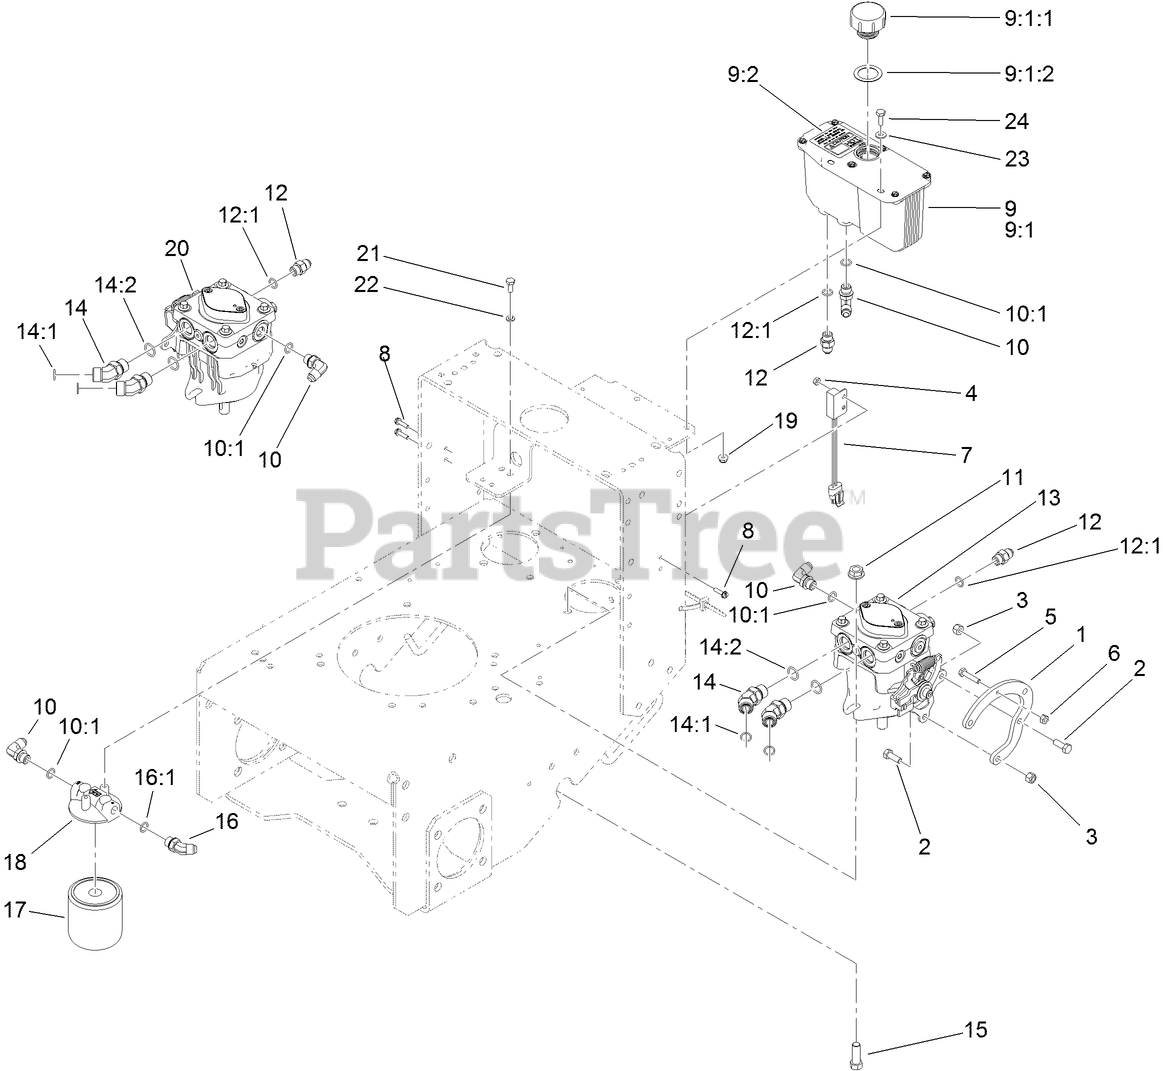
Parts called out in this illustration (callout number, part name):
1	BRACKET-ADAPTER, PUMP
2	SCREW-HH
3	NUT-LOCK, NI
4	NUT-LOCK, NI
5	SCREW-HH
6	NUT-HEX
7	SWITCH-PROXIMITY
8	SCREW-HWH
9	HYD RESERVOIR ASM
9:1	Reservoir-HYD
9:1:1	CAP-RESERVOIR, HYD
9:1:2	GASKET-CAP
9:2	DECAL-WARNING
10	FITTING-ELBOW, 90 DEG
10:1	O-RING
11	NUT-HF
12	FITTING-STRAIGHT
12:1	O-RING
13	HYD PUMP ASM
14	FITTING-HYD, 45 DEG
14:1	O-RING
14:2	O-RING
15	SCREW-HH
16	FITTING-ELBOW, 45 DEG
16:1	O-RING
17	FILTER-OIL, HYD
17	FILTER-OIL, HYD (WINTER)
18	HEAD-FILTER
19	NUT-HF
20	HYD PUMP ASM
21	SCREW-HH
22	WASHER-LOCK
23	WASHER-FLAT
24	SCREW-HH
